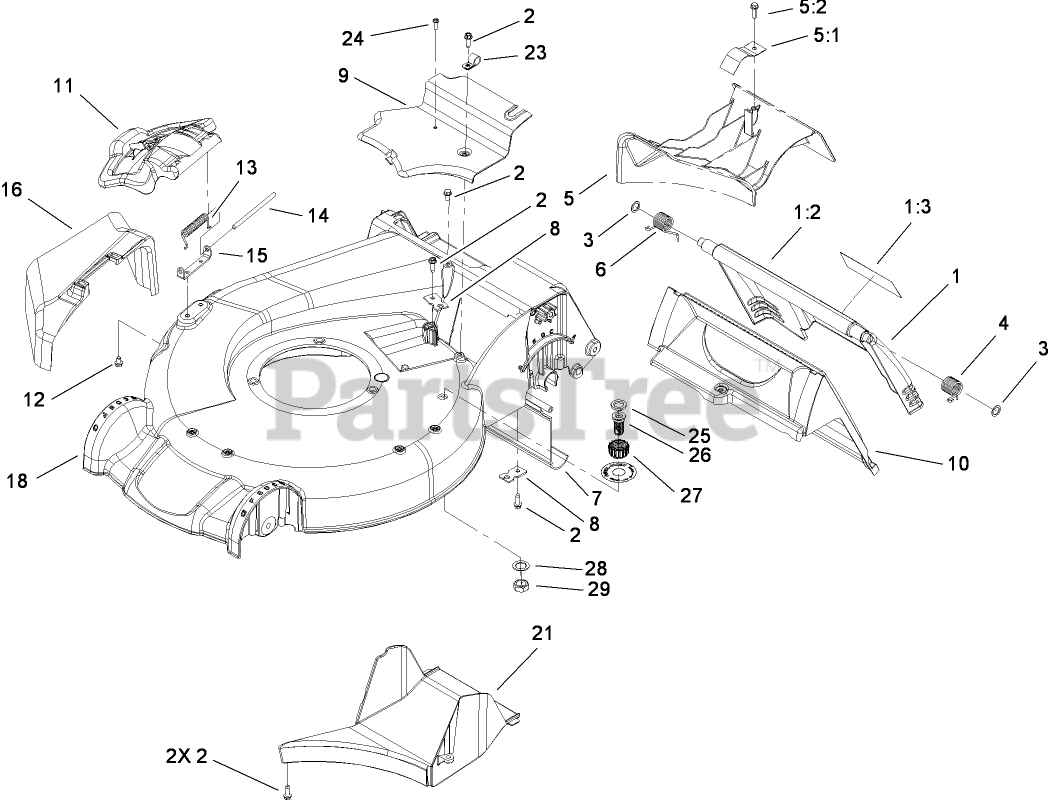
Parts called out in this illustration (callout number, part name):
1	REAR DOOR ASM
1:2	DECAL-WARNING
1:3	DECAL-WARNING
2	SCREW-HWHTF
3	WASHER-NYLON
4	SPRING-TORSION
5:2	SCREW-HWH
6	SPRING-TORSION
9	COVER-BELT
11	DISCHARGE DOOR ASM
12	SCREW-HWH
13	SPRING-TORSION
15	BRACKET-COVER
16	CHUTE-DISCHARGE, SIDE
18	HOUSING ASM
21	TUNNEL-DISCHARGE
23	CLAMP
25	WASHER-SEAL, WASHOUT PORT
26	PORT-WASHOUT
27	COUPLING-HOSE, WASHOUT PORT
28	WASHER-LOCK
29	NUT-JAM
